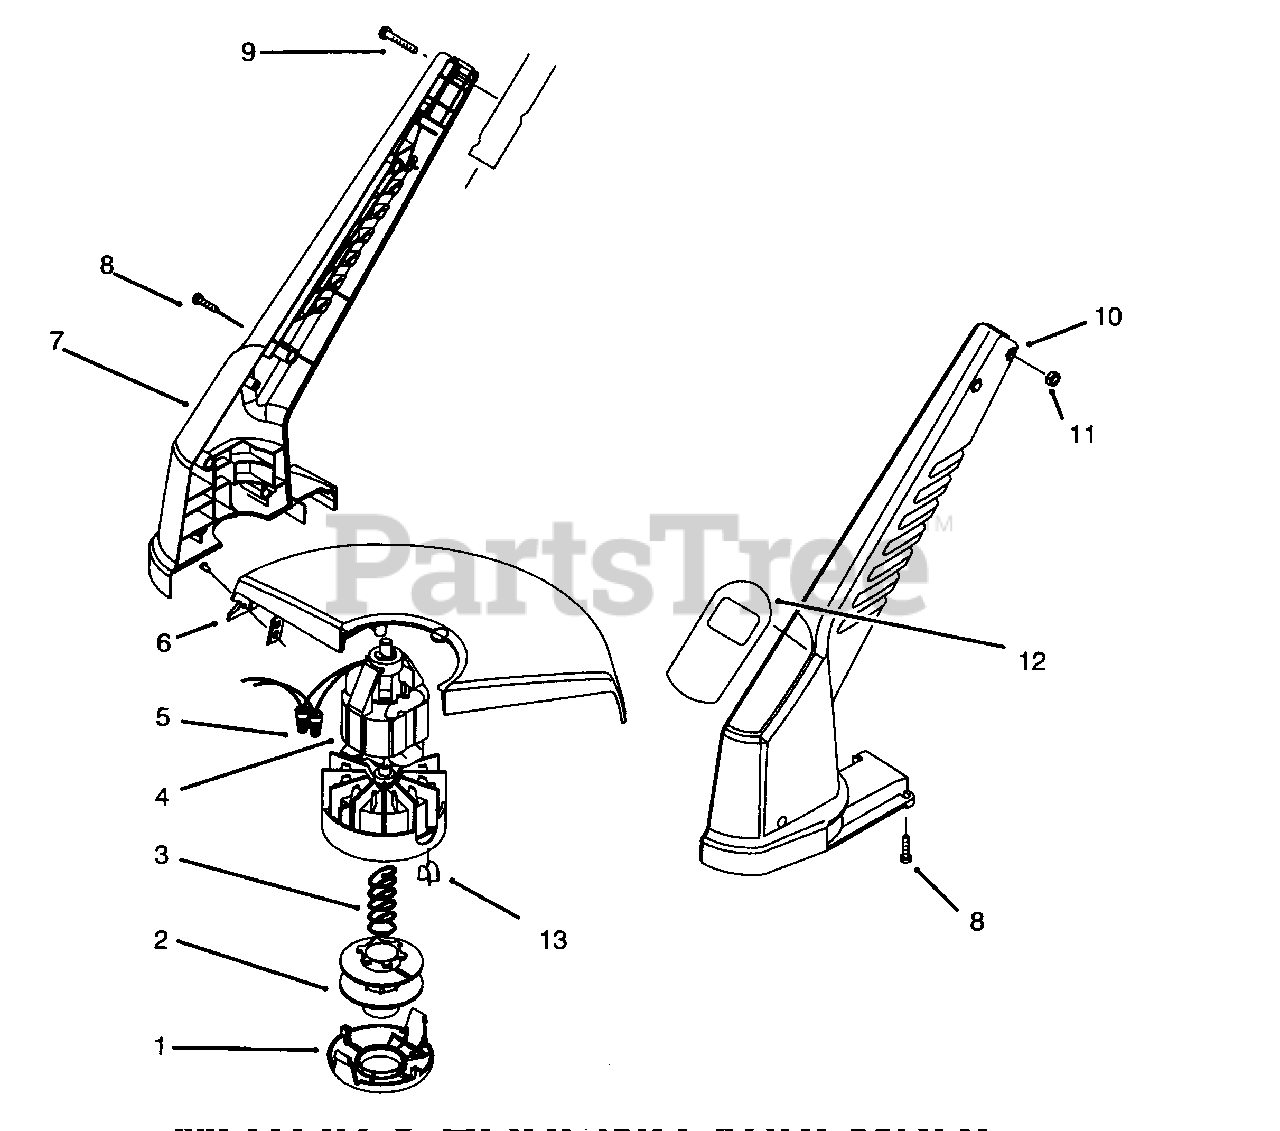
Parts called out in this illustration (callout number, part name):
4	Motor Assembly (Incl. Ref. #13)
5	Connector-Wire Nut
6	Shield-14"
7	Housing R.H.
8	Screw-Pan Hd. Tapping
9	Screw-Pan Hd.
10	Housing L.H.
12	Decal-14" Trimmer
